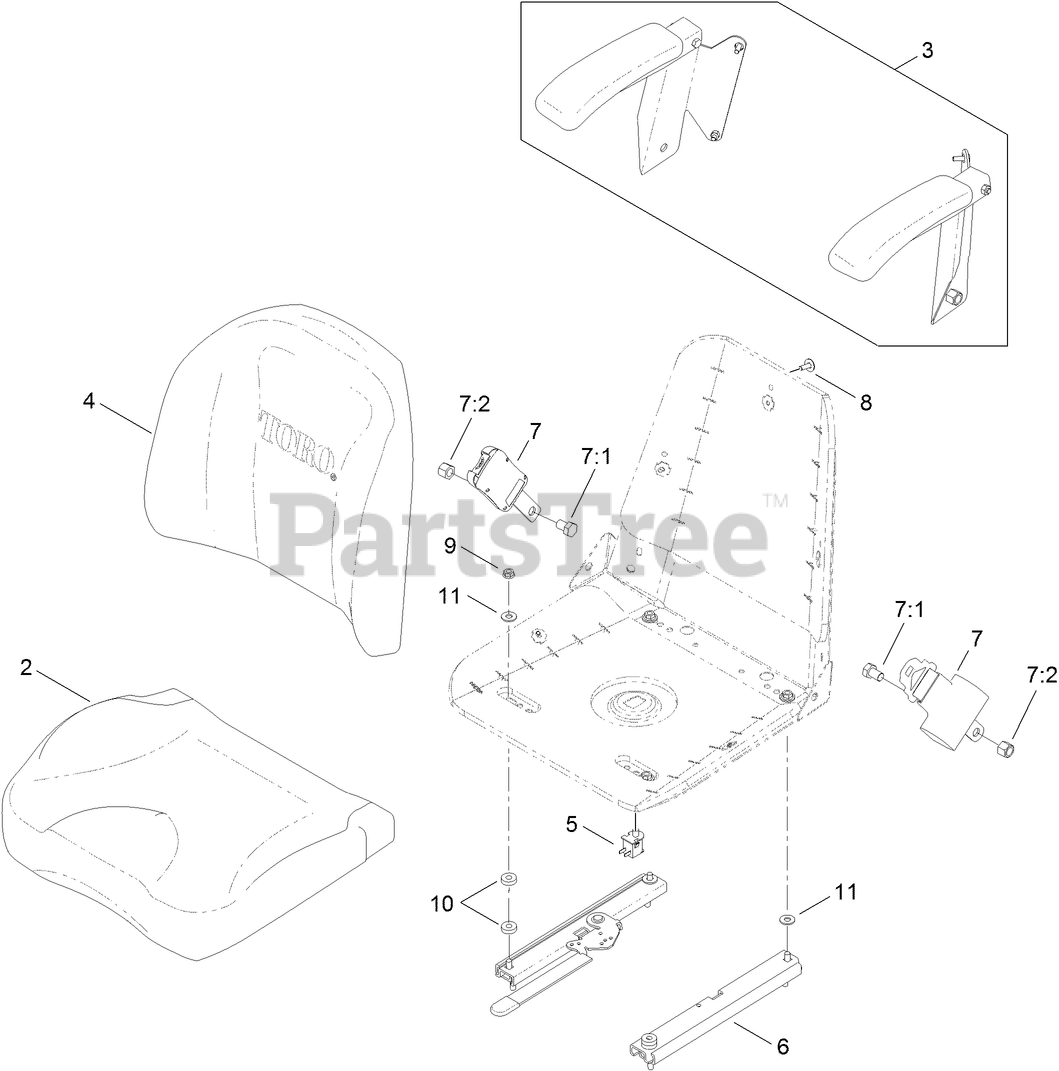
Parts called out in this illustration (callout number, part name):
2	CUSHION-SEAT, BOTTOM
3	ARMREST KIT
4	CUSHION-SEAT, BACK
5	SWITCH-BAIL
6	TRACK ASM
7	SEAT BELT KIT
7:1	SCREW-HH
7:2	NUT-LOCK, NI
8	BOLT-SEAT
9	NUT-HF
11	WASHER-FLAT
